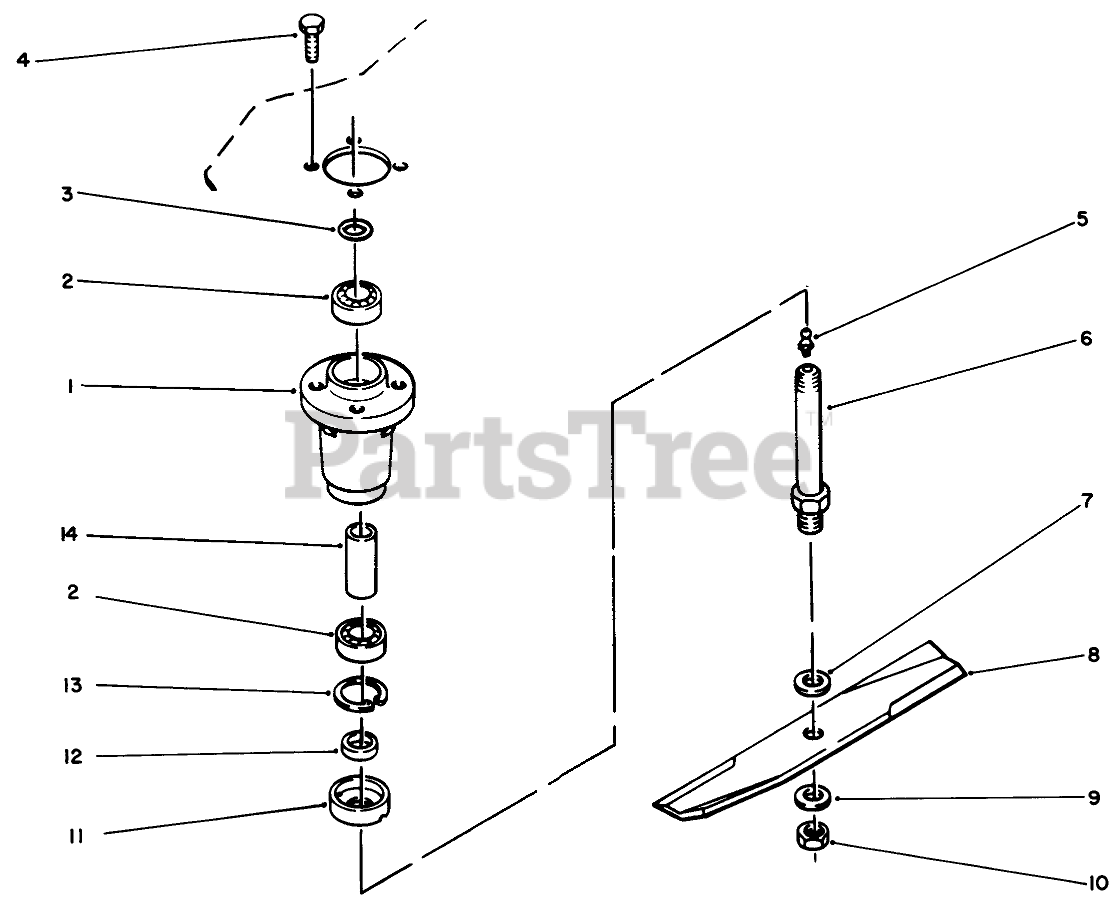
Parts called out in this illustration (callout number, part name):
1	HOUSING-SPINDLE
2	BEARING-BALL
3	O RING
4	Bolt
5	Zerk
6	SHAFT-SPINDLE
7	Washer
8	BLADE KIT (3- 79-2920)
9	Washer
10	Nut
11	CUP-SPINDLE
12	SPACER-BLADE
13	Ring-Snap
